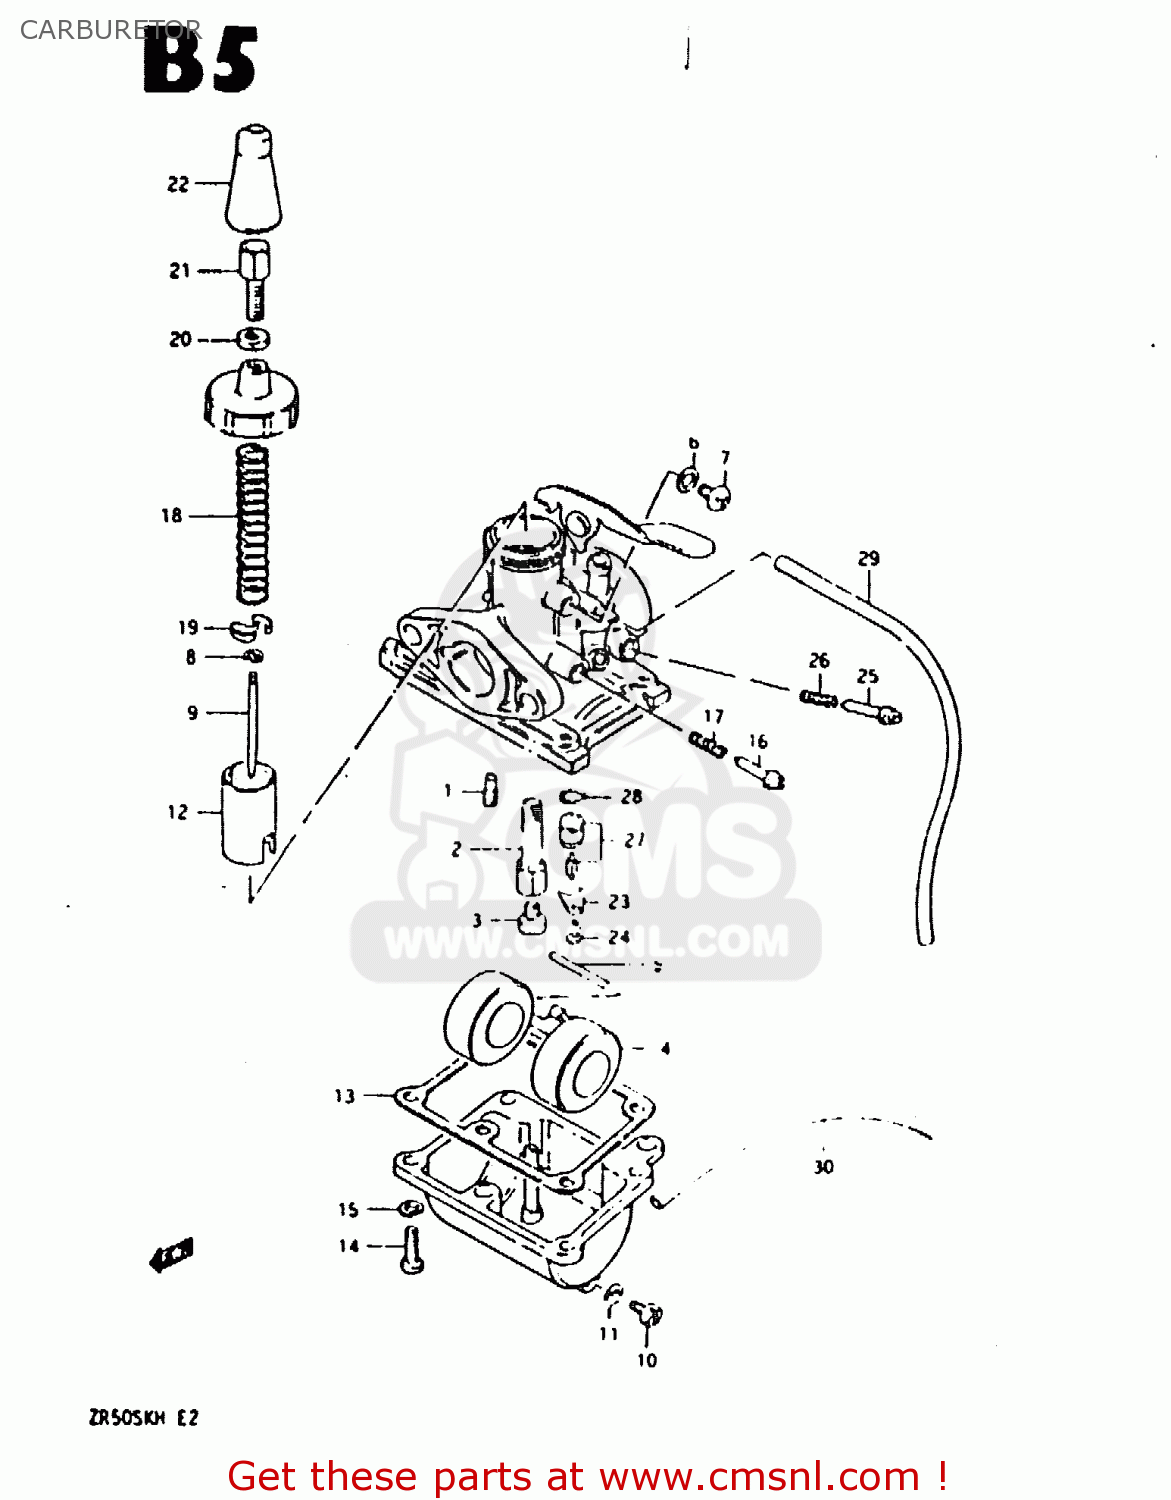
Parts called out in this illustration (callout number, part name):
1	JET,PILOT
2	JET, NEEDLE (F-1)
3	JET,MAIN(65)
4	FLOAT
5	PIN,FLOAT
6	RING
7	SCREW
8	CLIP,NEEDLE
9	NEEDLE,JET
10	PLUG
11	GASKET,DRAIN,PLUG (NAS)
12	VALVE, THROTTLE (CA:1.5)
13	GASKET,FLOAT CHAMBER (NAS)
14	SCREW
15	LOCK WASHER
16	SCREW,THROTTLE STOP
17	SPRING
18	SPRING,THROTTLE VALVE RETURN
19	PLATE
20	NUT
21	ADJUSTER,CABLE
22	CAP,RUBBER
23	PLATE,NEEDLE VALVE FITING
24	SCREW
25	SCREW,AIR
26	SPRING
27	VALVE ASSY,NEEDLE
28	O RING
29	HOSE
30	HOSE
